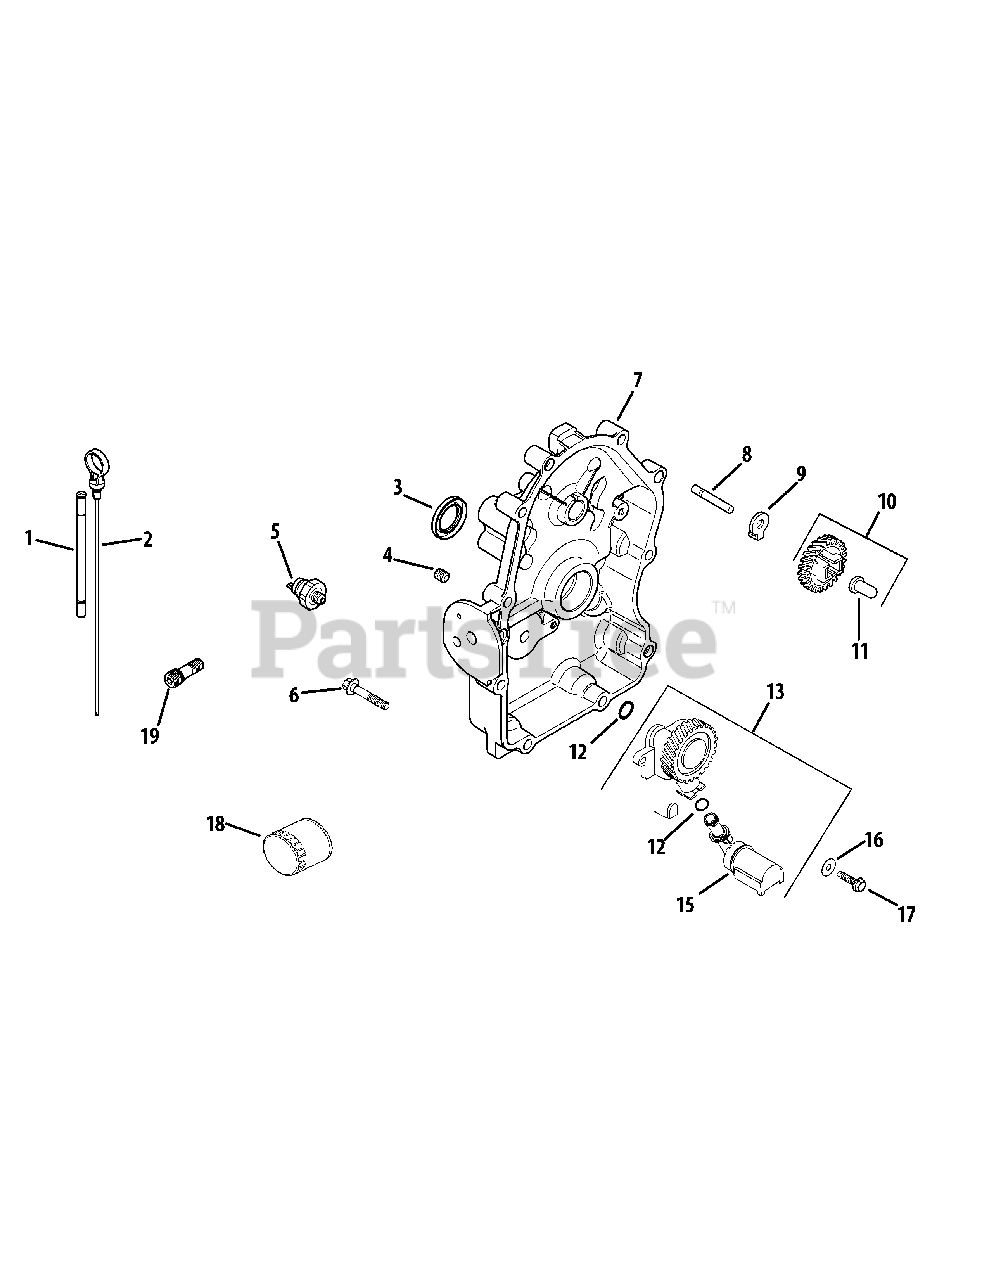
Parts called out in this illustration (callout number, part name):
1	Dipstick/Dipstick Tubes Kit
4	Countersink Pipe Plug, 1/8
5	Oil Pressure Switch
6	Flange Screw, M8 x 1.25 x 45
7	Closure Plate Assembly
8	Governor Gear Shaft
10	Governor Gear Kit w/ Pin
11	Governor Regulating Pin
13	Oil Pump Assembly Kit
14	Oil Pick-Up O-Ring
16	Flat Washer, 1/4 x 5/8
17	Thread Forming Screw
19	Oil Filter Nipple
